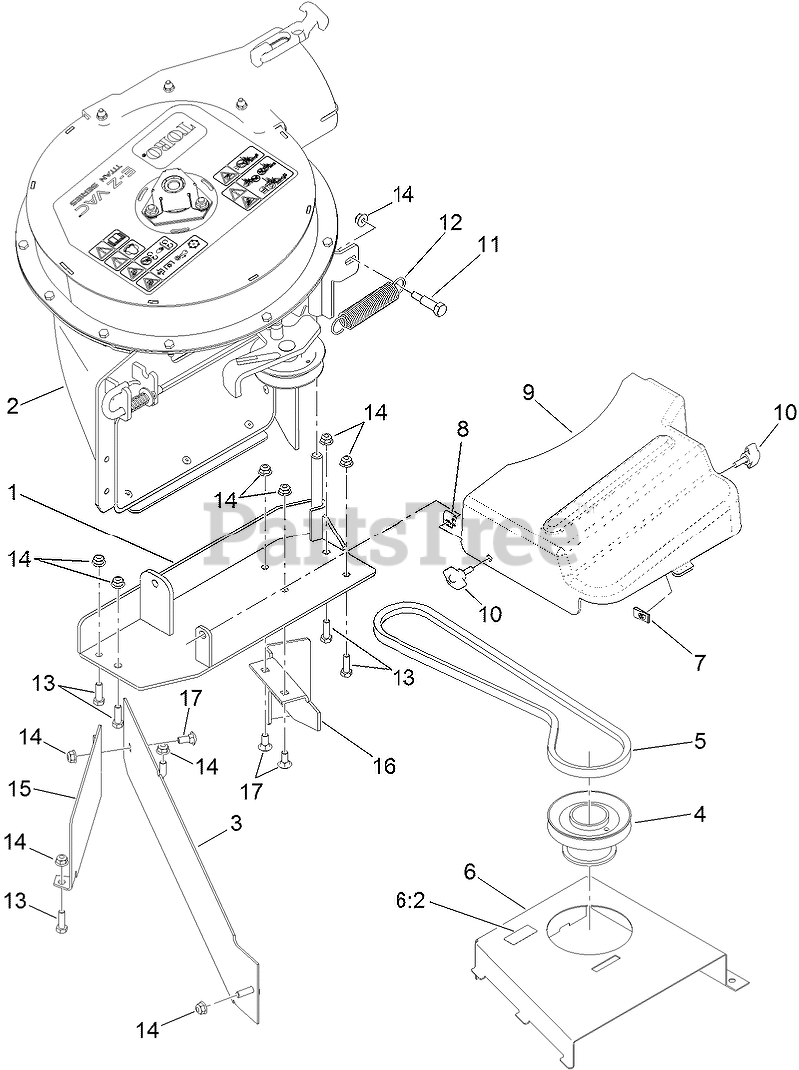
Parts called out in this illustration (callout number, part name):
1	SUPPORT-BLOWER
2	BLOWER HOUSING ASM
4	PULLEY-BAGGER
5	BELT-V
6	COVER ASM
6:2	DECAL-DANGER
7	NUT-SPEED
8	NUT-SPEED
9	COVER-BELT
11	SCREW-SHOULDER, HH
12	SPRING-EXTENSION
13	SCREW-HH
14	NUT-HF, NI
15	GUARD-BAFFLE
16	BAFFLE-CUTOFF
17	BOLT-CARR
